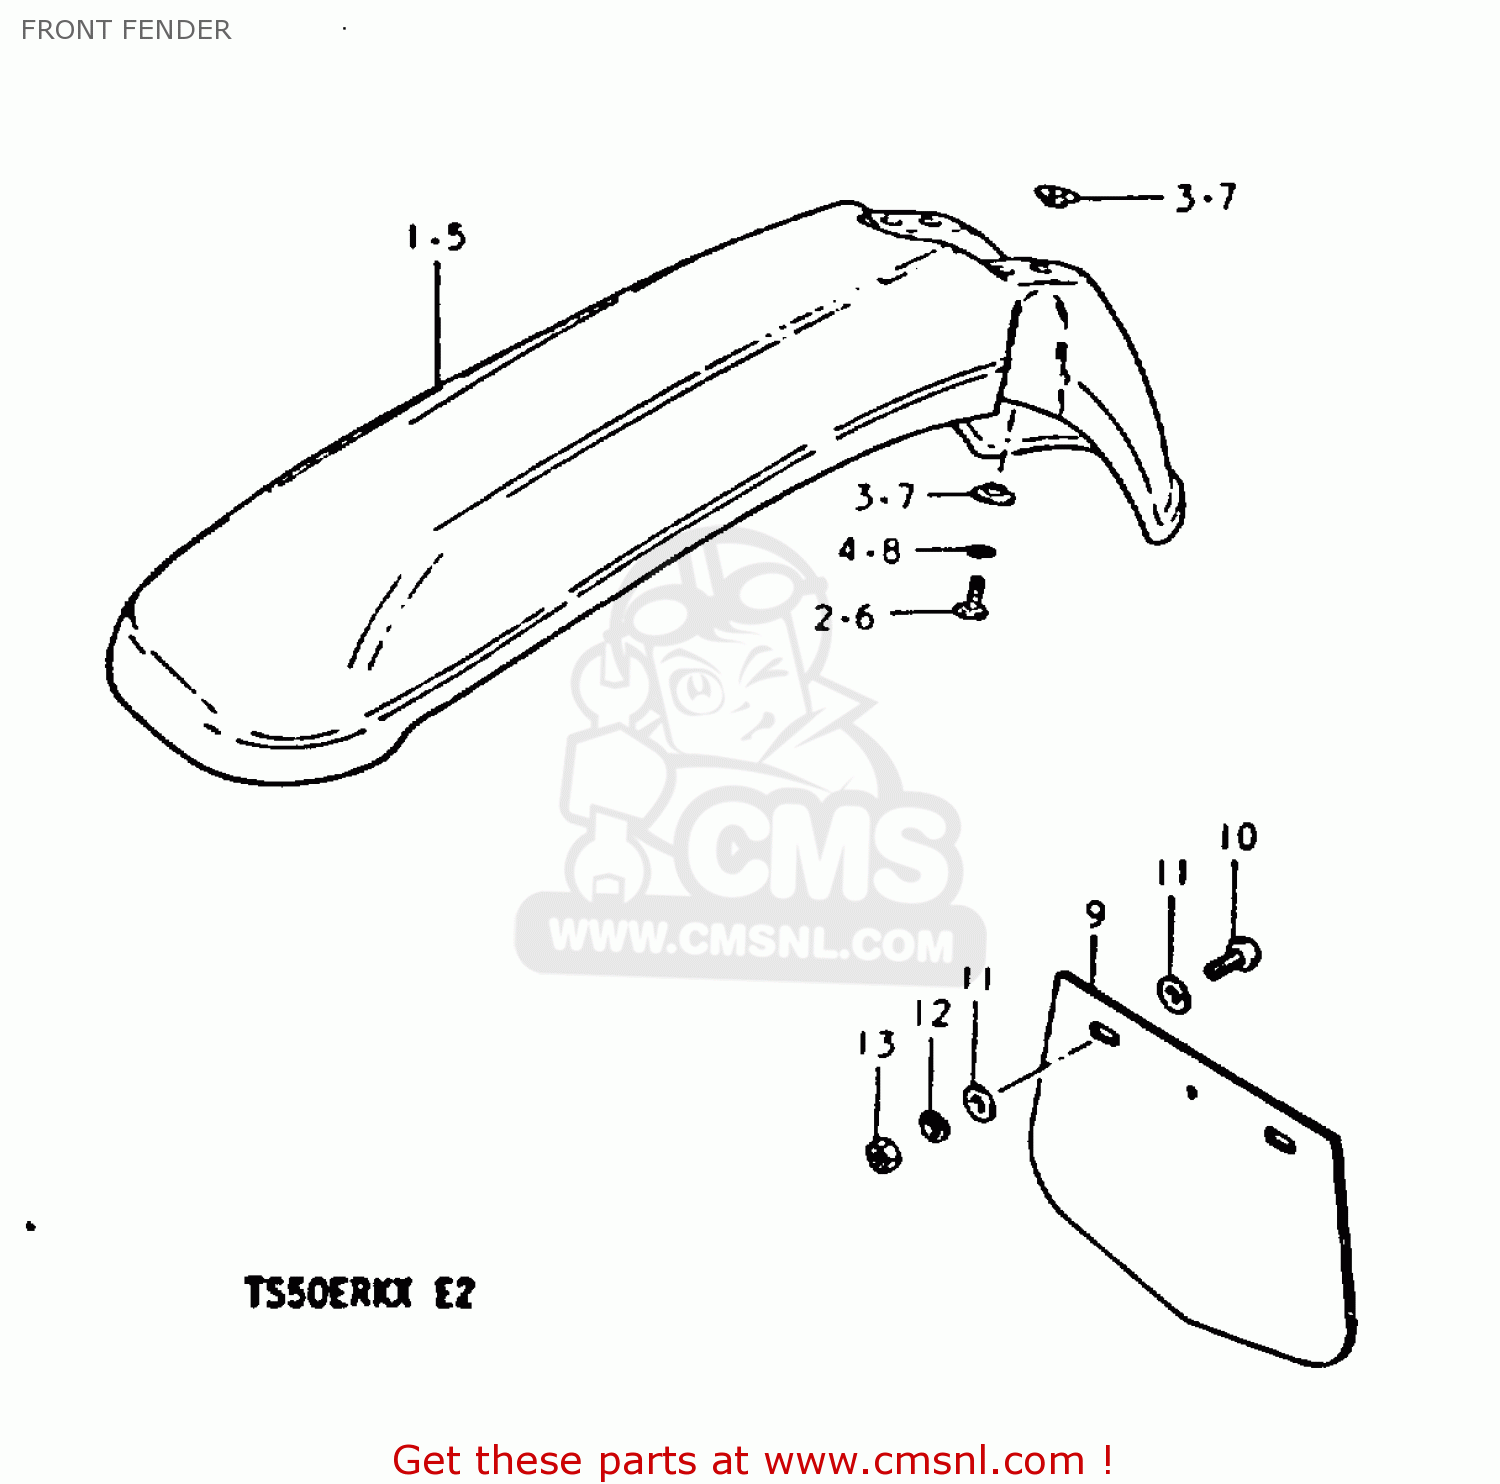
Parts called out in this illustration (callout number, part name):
1	FENDER,FRONT
2	BOLT, UPPER
3	SPACER
4	LOCK WASHER
